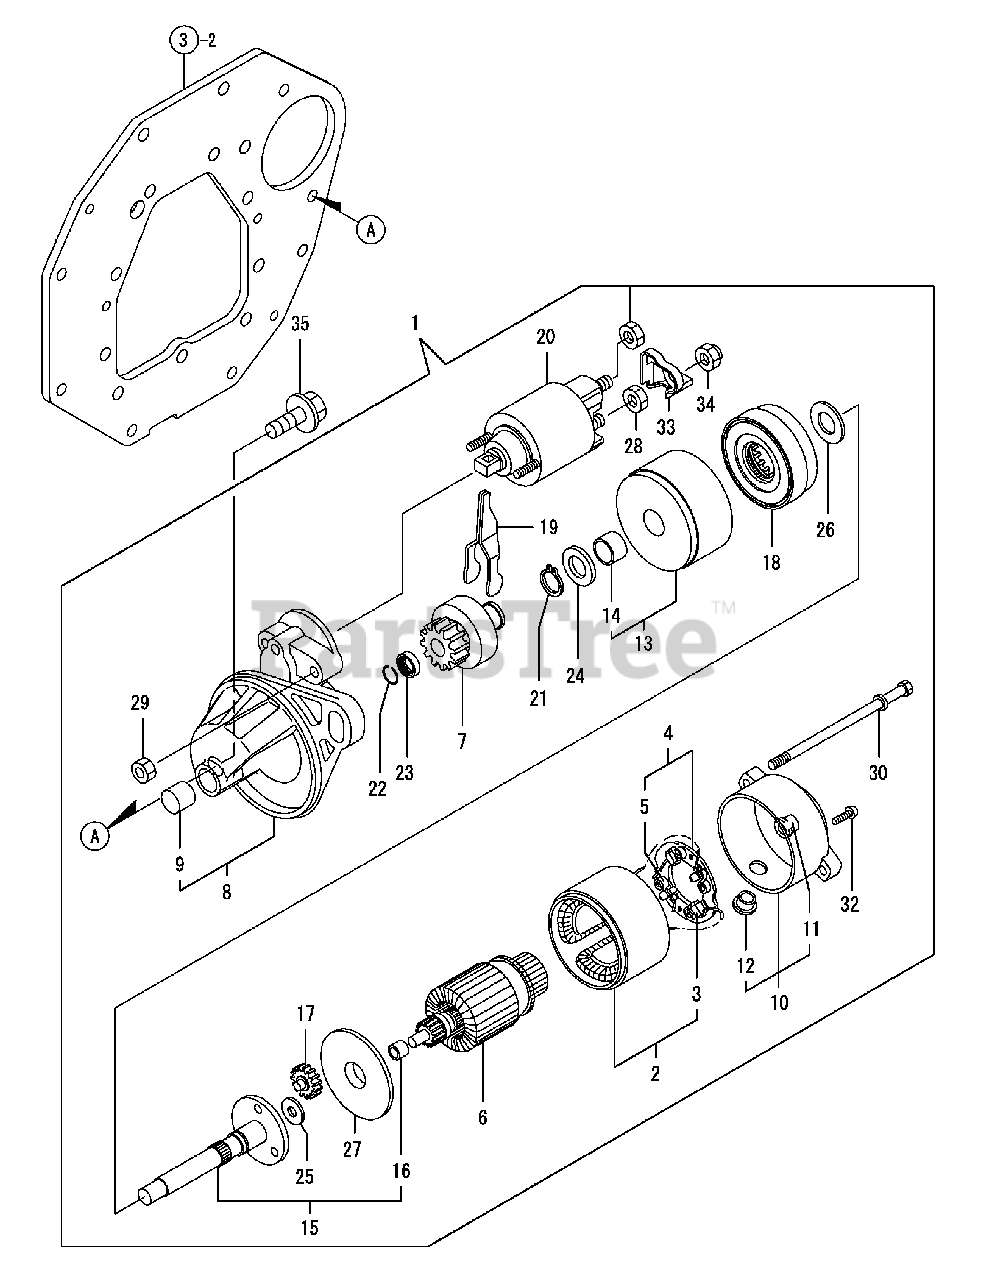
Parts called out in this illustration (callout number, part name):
2	Coil Assembly, Field
4	Holder Assembly
6	Armature Assembly
7	Clutch Sub-Assembly
8	Housing Assembly, Starter
9	Needle Bearing
10	Frame Assembly
13	Bearing Sub-Assembly
15	Shaft Sub-Assembly
20	Switch, Emergency
32	Screw, M 4 x 6
33	Cover Set, Terminal
35	Bolt, M 10 x 25 Plated
